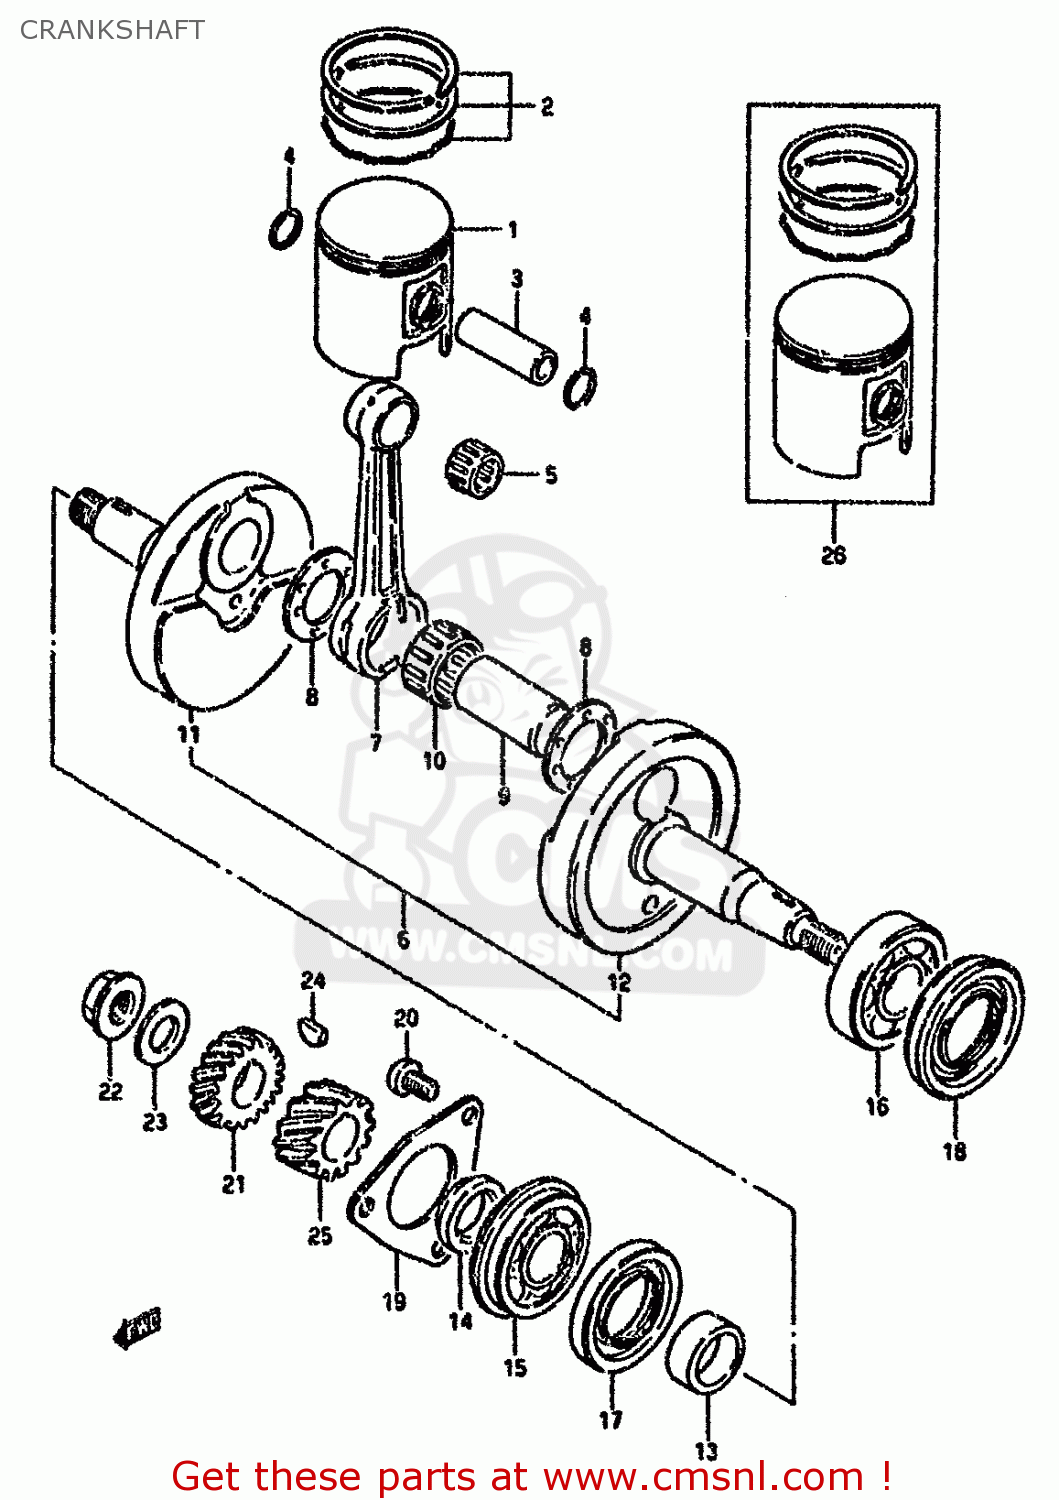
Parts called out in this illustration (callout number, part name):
1	PISTON
2	RING SET,PISTON
3	PIN,PISTON
4	RING,SNAP
5	ROLLER BEARING (12X16X1
6	CRANKSHAFT ASSY
7	CONNECTING ROD
8	WASHER (20X34X1)
9	PIN,CRANK
10	BEARING(20X26X16)
11	CRANKSHAFT,RH
12	CRANKSHAFT,LH
13	SPACER(20X28X10)
14	SPACER(16X27X7)
15	BEARING(20X47X14)
16	BEARING(20X47X14)
17	SEAL,OIL(28X47X7.3)
18	SEAL,OIL(19.6X37X8)
19	RETAINER
20	SCREW
21	GEAR,PRIMARY DRIVE
22	NUT
23	WASHER
24	KEY
25	GEAR,TACHOMETER DRIVE
26	PISTON SET(OS:0.5)
